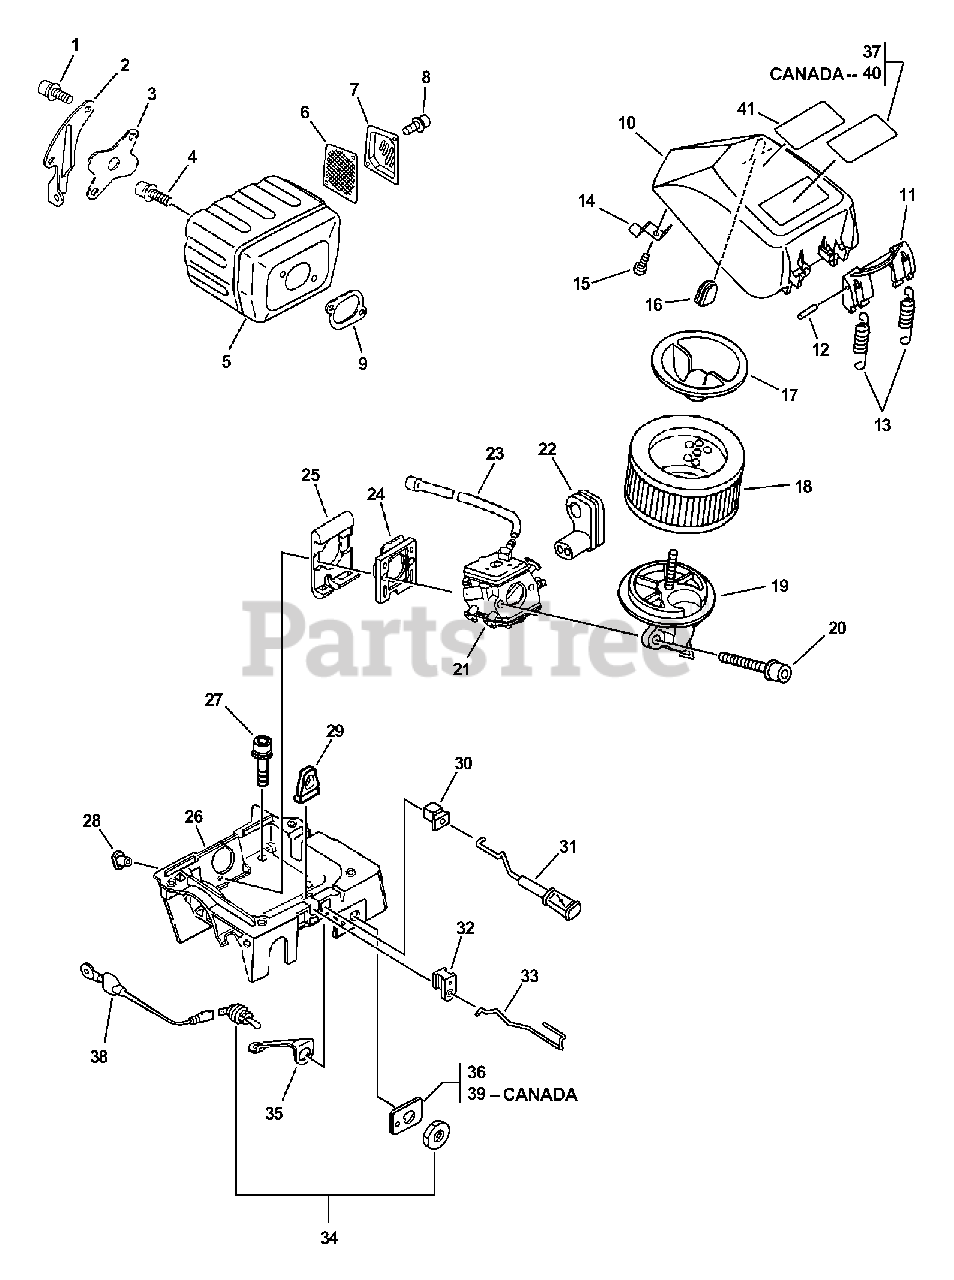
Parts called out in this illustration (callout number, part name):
1	SCREW - 5X14
2	BRACKET, MUFFLER
3	COVER, MUFFLER
4	SCREW - 5X20
5	MUFFLER
6	SCREEN, SPARK ARRESTOR
7	GUIDE, EXHAUST
8	SCREW - 4X10
9	GASKET, EXHAUST
10	COVER, AIR FILTER
12	PIN - 3X12
14	SPRING, FLAT
15	SCREW - 4X10
17	COVER, AIR FILTER
18	FILTER, AIR
19	MOUNT, AIR FILTER
20	SCREW - 5X50
21	CARBURETOR
22	GROMMET
23	PIPE - IMPULSE
24	INSULATOR, INTAKE
25	BRACKET
26	CASE, CARBURETOR
27	SCREW - 5X20
29	CUSHION
31	ROD, CHOKE
32	GUIDE, THROTTLE ROD
33	ROD, THROTTLE
34	IGNITION SWITCH ASSY
35	TERMINAL - GROUND
36	LABEL - STOP
37	LABEL - MODEL CS-670
38	LEAD - GROUND
39	LABEL - SWITCH
40	LABEL - MODEL CS-670
41	LABEL - ATTENTION
